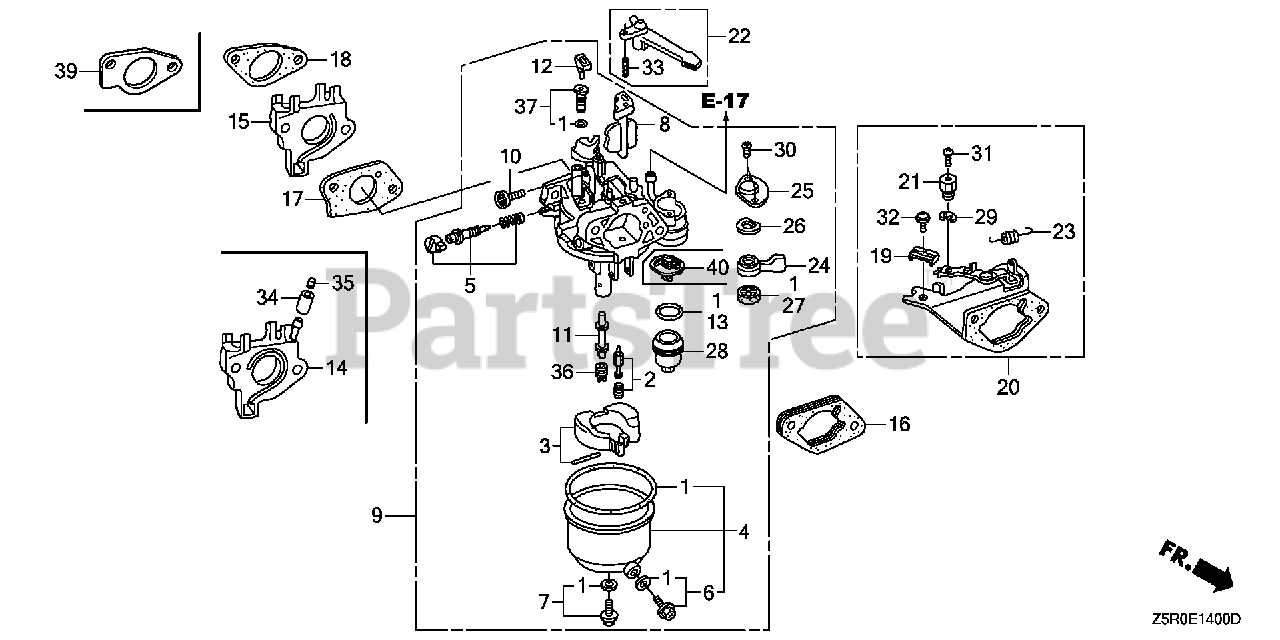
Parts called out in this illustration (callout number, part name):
1	GASKET SET (INCLUDES 16173-001-004)
2	VALVE SET, FLOAT
4	CHAMBER SET, FLOAT
5	SCREW SET, PILOT
6	SCREW SET, DRAIN
7	SCREW SET
9	CARBURETOR ASSY. (BE85B B)
10	SCREW, THROTTLE STOP
11	NOZZLE, MAIN
12	COLLAR, SETTING
13	GASKET, FUEL STRAINER CUP
15	INSULATOR, CARBURETOR
16	SPACER, CARBURETOR
17	GASKET, CARBURETOR
18	GASKET, INSULATOR
22	LEVER, CHOKE (STD)
24	LEVER, PETCOCK
25	PLATE, LEVER SETTING
26	SPRING, PETCOCK LEVER
27	GASKET, PETCOCK
28	CUP, FUEL STRAINER
30	SCREW, PAN (3X6)
33	PIN, SPRING (2X12)
36	JET, MAIN (#88)
36	JET, MAIN (#90)
36	JET, MAIN (#92)
37	JET SET, PILOT (#45)
